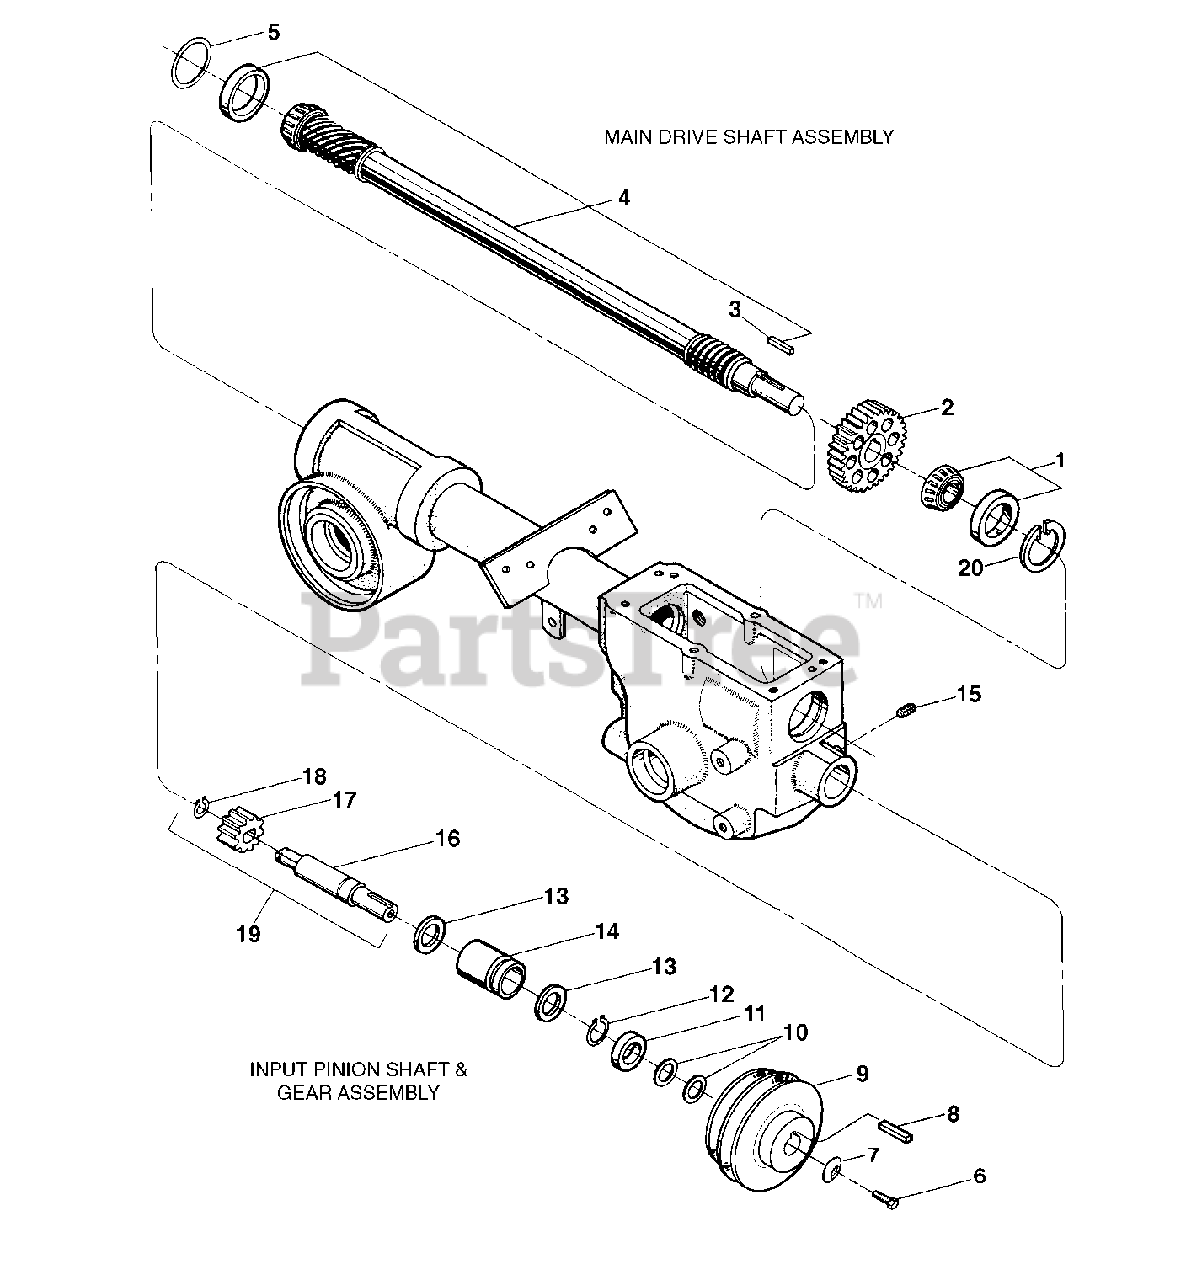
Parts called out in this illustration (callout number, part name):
1	Bearing-tapered roller with race
2	Gear-spur, main drive shaft
3	Key-3/16 sq. x 1
4	Drive Shaft-with integral, single-lead worm at front and six-lead worm at rear
5	Shim-rear bearing cap, .010 thick
5	Shim-same as above, but .030 thick
5	Shim-same as above, but .005 thick
6	Screw-hex hd., 5/16-24 x 1-1/8
7	Washer-disc spring (concave surface faces pulley)
8	Key-3/16 sq. x 1-1/2
9	Pulley-transmission drive
10	Washer-support
11	Oil Seal-input pinion shaft, front
12	Ring-retaining (snap ring), external
13	Washer-thrust
14	Bushing
15	Set Screw-5/16-18 x 3/8
16	Input Pinion-steel shaft
17	Gear-input pinion
18	Retainer-snap ring, external
19	Pinion Assy-
20	Retainer-snap ring, internal
